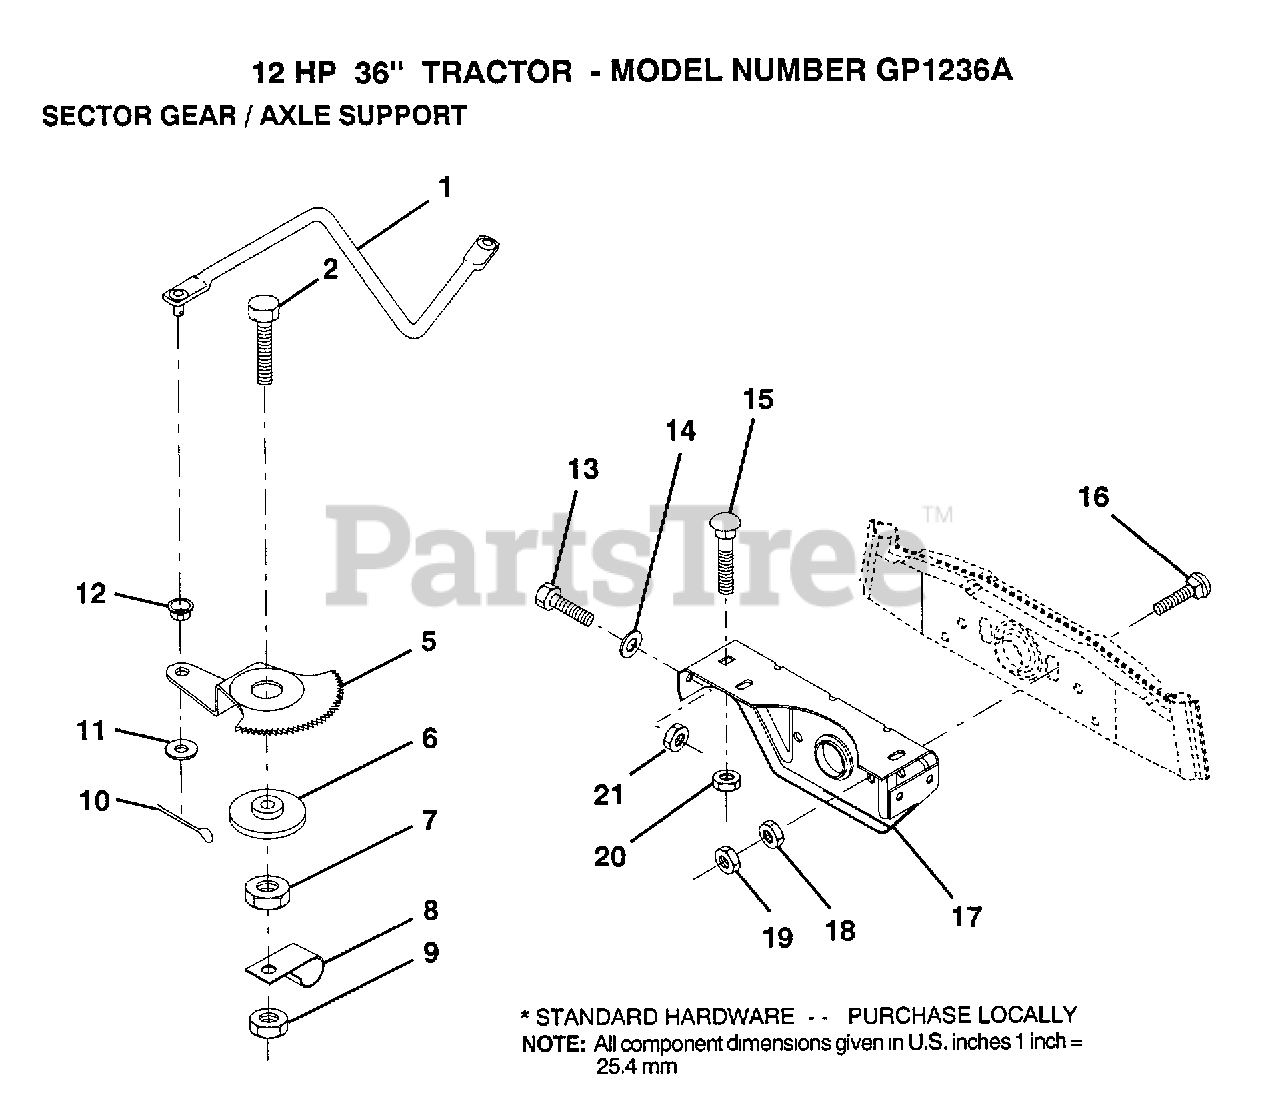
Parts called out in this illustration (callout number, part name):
1	DRAG LINK
2	"BOLT,HEX"
5	GEAR SECTOR
6	BUSHING
7	NUT
8	CLIP INSULATOR
9	NUT LTV
10	COTTER PIN
11	WASHER
12	BUSHING.DRAGLINK
13	BOLT
14	WASHER
15	BOLT
16	BOLT
17	"SUPT,FRT AXLE"
18	NUT.HEX.3/8-16UNC
19	LOCKNUT
